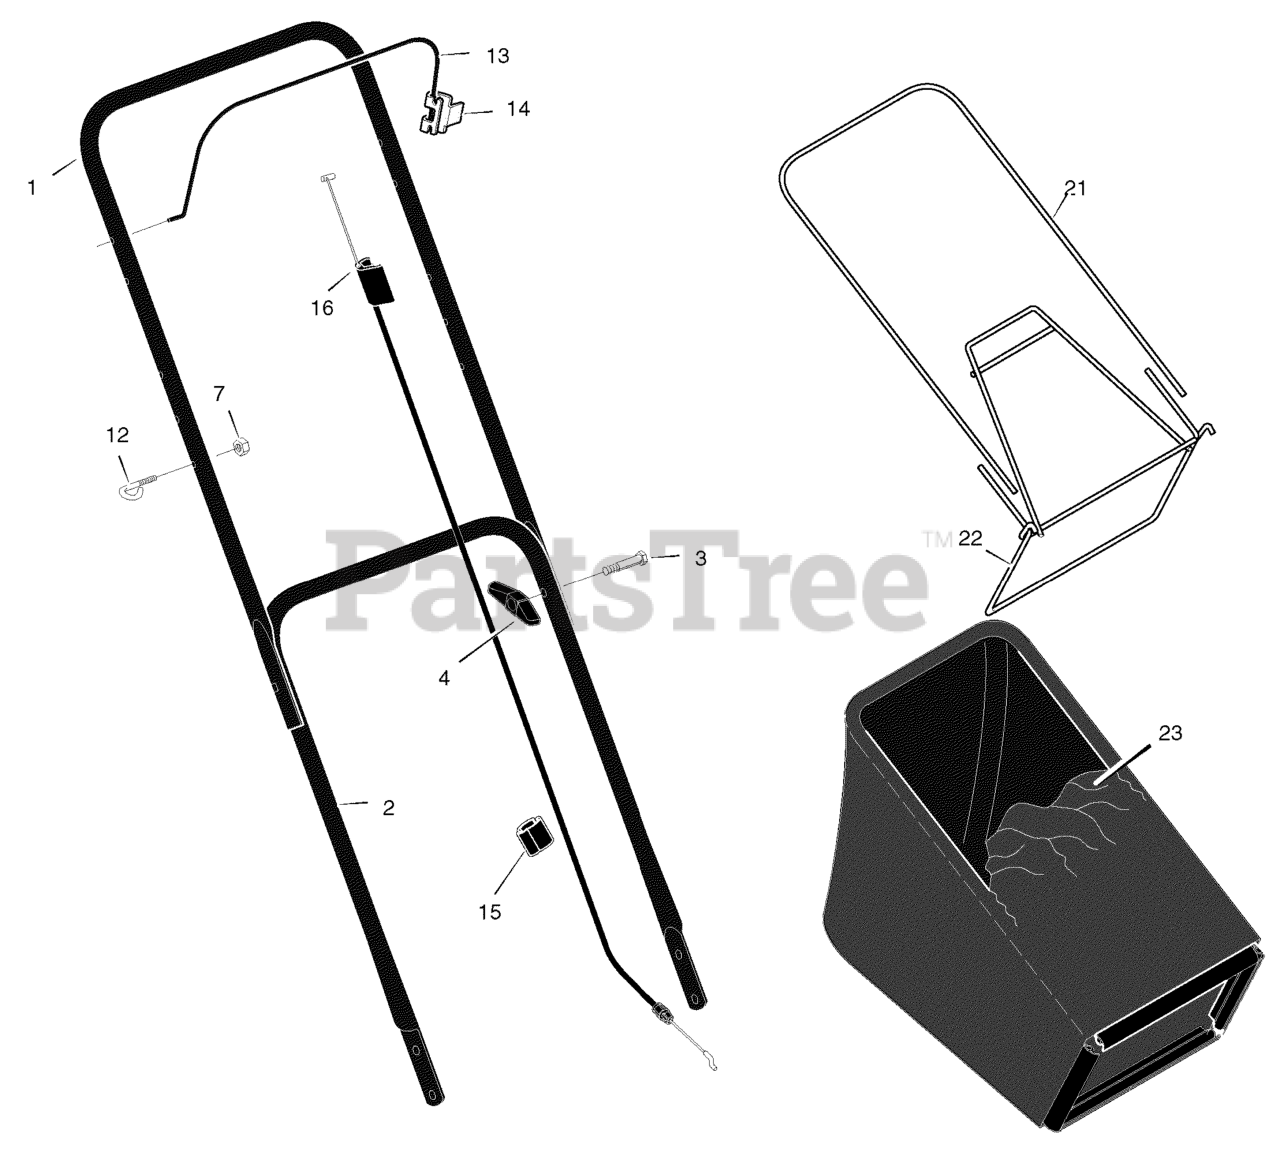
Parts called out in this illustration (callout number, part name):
1	Handle, Upper (Black)
2	Handle, Lower (Black)
4	Knob, Plastic
7	Locknut
12	Guide, Rope
13	Engine Stop Lever
14	Bracket, Stop Lever
15	Fastener, Cable
16	Engine Stop Cable
21	Frame, Top
22	Frame Assembly
23	Bag, Cloth
